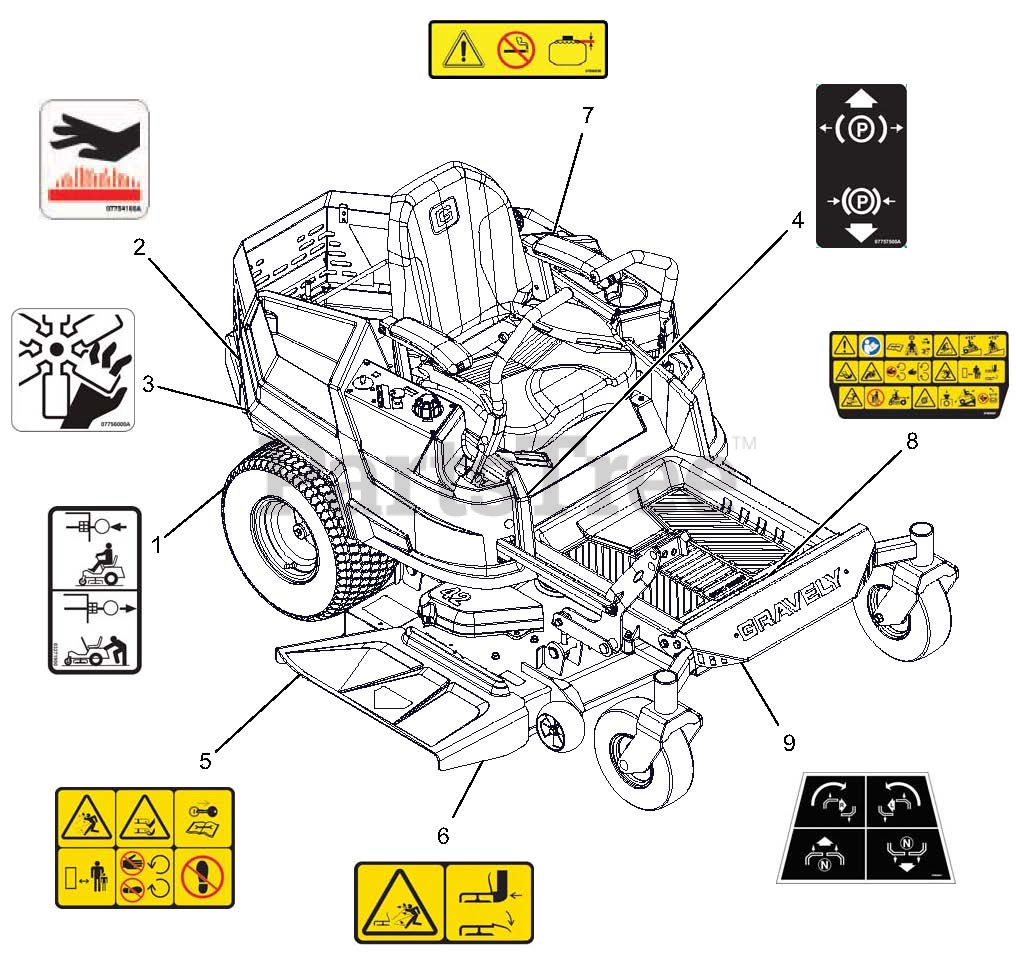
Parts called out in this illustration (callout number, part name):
1	DECAL, TRANSMISSION DISCONNECT
2	DECAL, HOT SURFACE
3	DECAL, DANGER FAN
4	DECAL, PARKING BRAKE LEVER
5	DECAL, SAFETY - MOWER DECK
6	DECAL, SAFETY - DECK GUARDING
7	DECAL-FUEL, WARNING
8	DECAL, MAIN SAFETY
9	DECAL, STEERING
